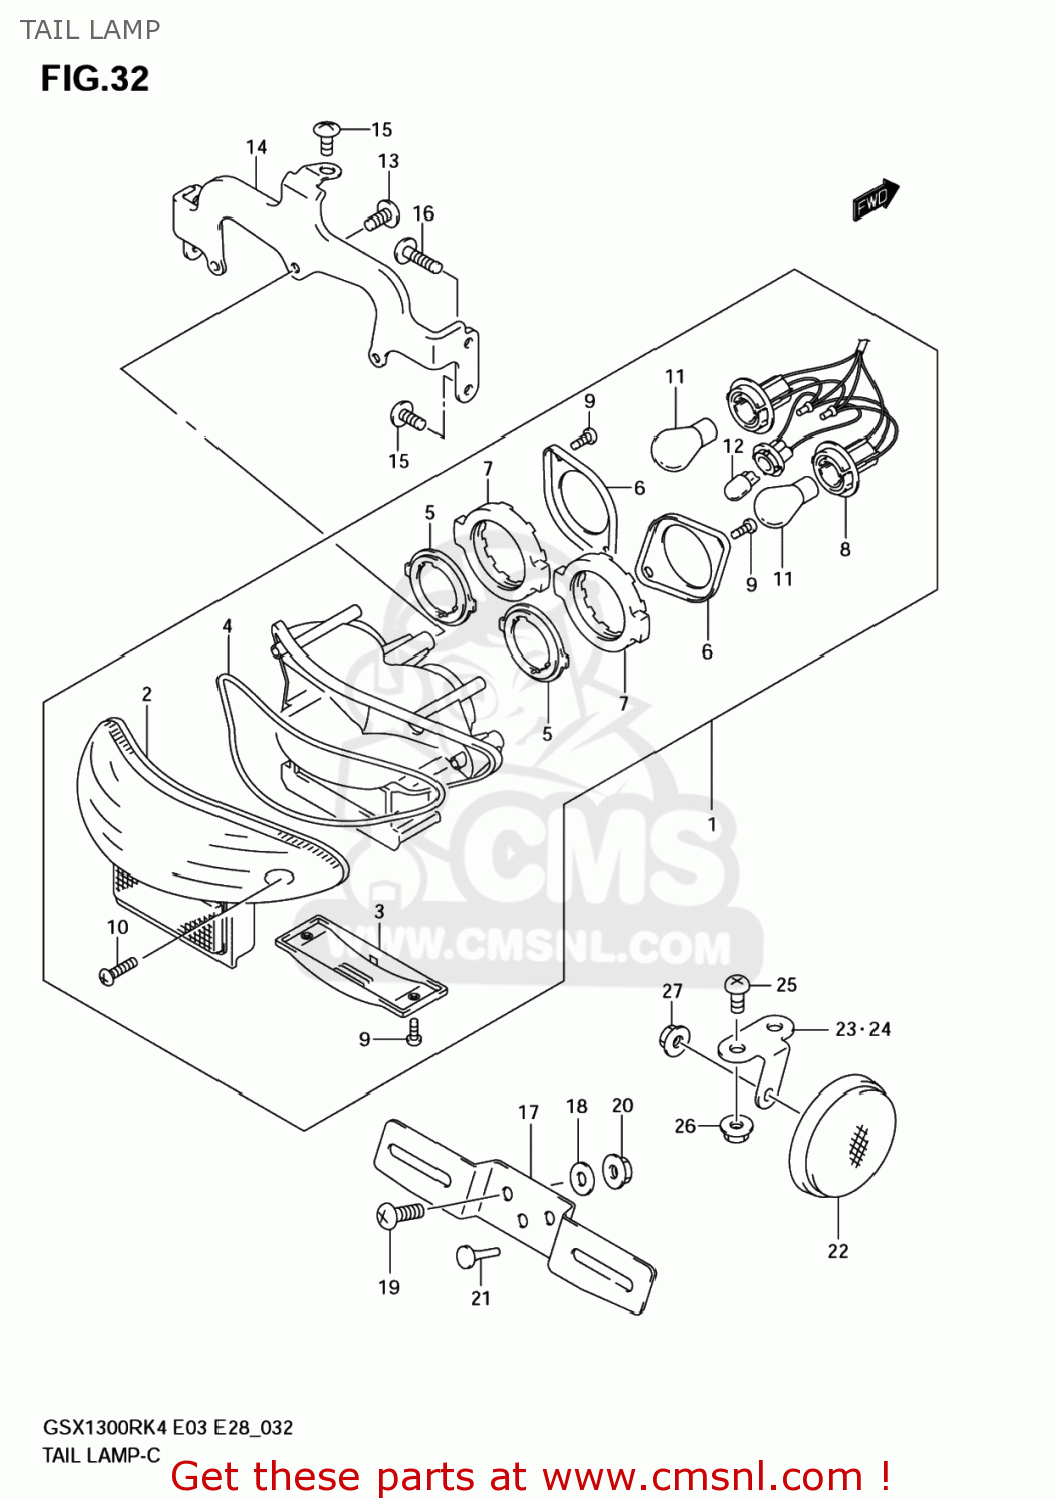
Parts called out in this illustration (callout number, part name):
1	LAMP ASSY,RR COMBINATION
2	LENS
3	LENS,LICENSE LAMP
4	GASKET (NAS)
5	PLATE NO.1
6	PLATE NO.2
7	CUSHION
8	SOCKET & CORD
9	SCREW
10	SCREW
11	BULB(12V21/5W)
12	BULB(12V5W)
13	SCREW
14	BRACKET,RR COMBINATION LAMP
15	SCREW
16	SCREW
17	BRACKET,LICENSE PLATE
18	WASHER(6.5X20X1.6)
19	SCREW
20	NUT
21	CUSHION
22	REFLECTOR ASSY,RR SIDE
23	BRACKET,RR SIDE RR,R
24	BRACKET,RR SIDE RR,L
25	SCREW
26	NUT
27	NUT
